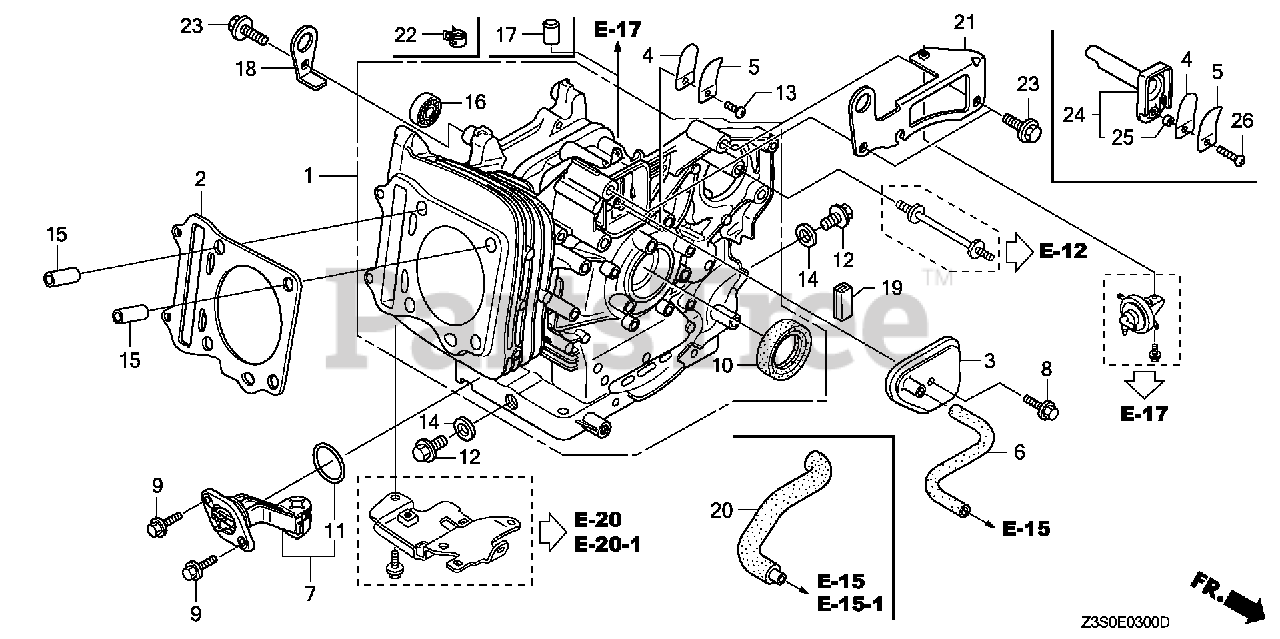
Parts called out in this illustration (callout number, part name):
1	CYLINDER ASSY.
2	GASKET, CYLINDER HEAD
3	COVER, BREATHER
4	PLATE, VALVE
5	STOPPER, VALVE
7	SWITCH ASSY., OIL LEVEL
8	BOLT, FLANGE (6X14)
9	BOLT, FLANGE (6X18) (CT200)
10	OIL SEAL (35X52X8)
11	O-RING (31.8X2.4)
12	BOLT, DRAIN PLUG (20MM)
14	WASHER, DRAIN PLUG (20MM)
15	PIN A, DOWEL (12X20)
16	BEARING, RADIAL BALL (6203)
18	HANGER, ENGINE
19	FILTER, BREATHER
20	TUBE, BREATHER
21	STAY, PETCOCK
23	BOLT, FLANGE (8X18) Use from Frame SN 1256673.
24	INSULATOR, BREATHER VALVE
25	COLLAR, AIR CLEANER
26	SCREW, PAN (5X14)
